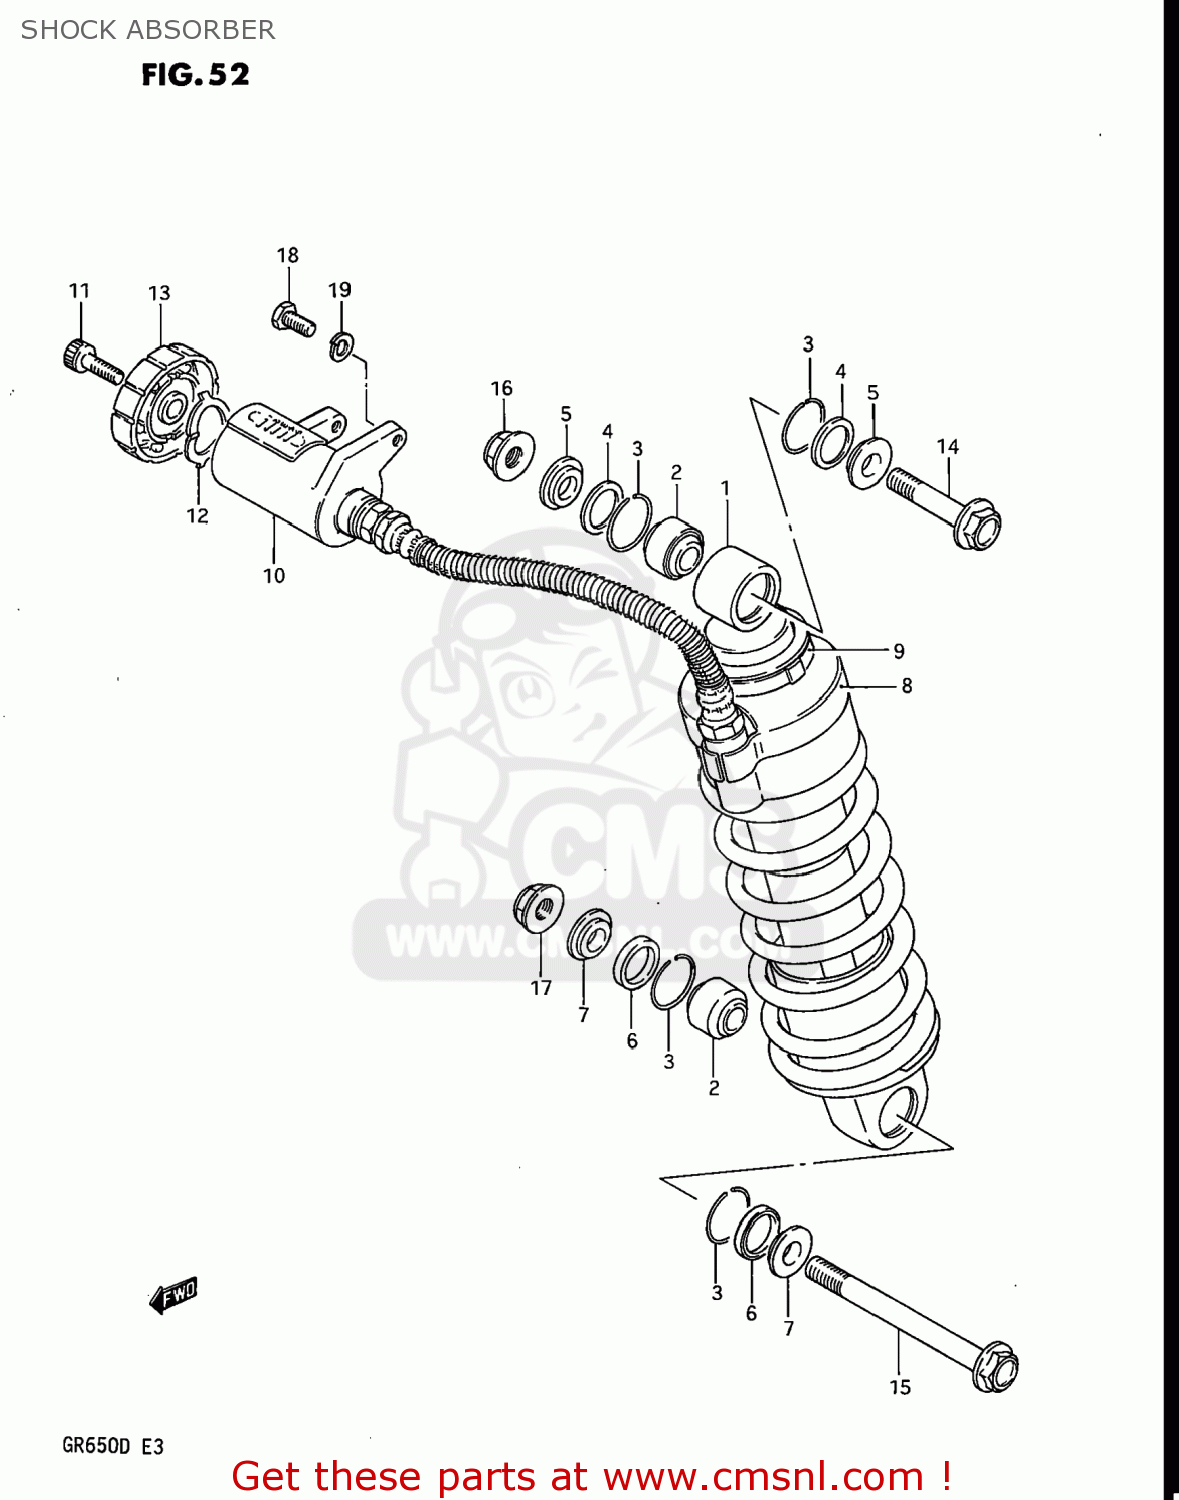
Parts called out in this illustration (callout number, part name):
1	ABSORBER ASSEMBLY,REAR SHOCK
2	BEARING
3	RING
4	DUST SEAL
5	SPACER
6	SEAL,DUST
7	COLLAR
8	COVER
9	BAND
10	SPRING ADJUSTER
11	BOLT
12	PLATE SET
13	LEVELING PLATE
14	BOLT(10X50)
15	BOLT(10X120)
16	NUT
17	NUT
18	BOLT, UPPER
19	LOCK WASHER
